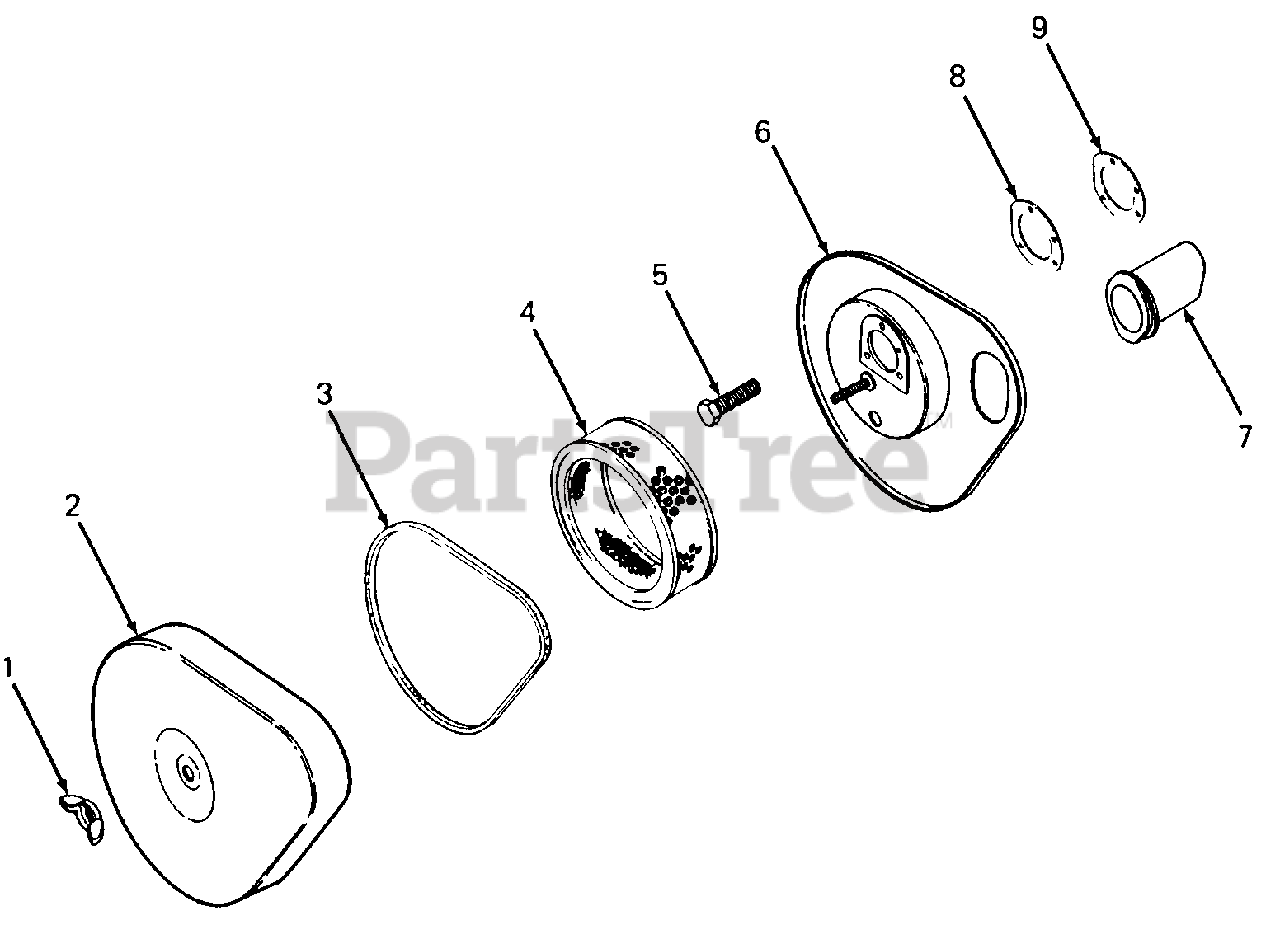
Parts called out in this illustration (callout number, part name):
1	Wing Nut, 1/4-20
2	Cover, Air Cleaner
4	Element
5	Screw, Hex Hd, 10-32 X 15/16 Lg
6	Base, Air Cleaner
8	Gasket, Air Horn
